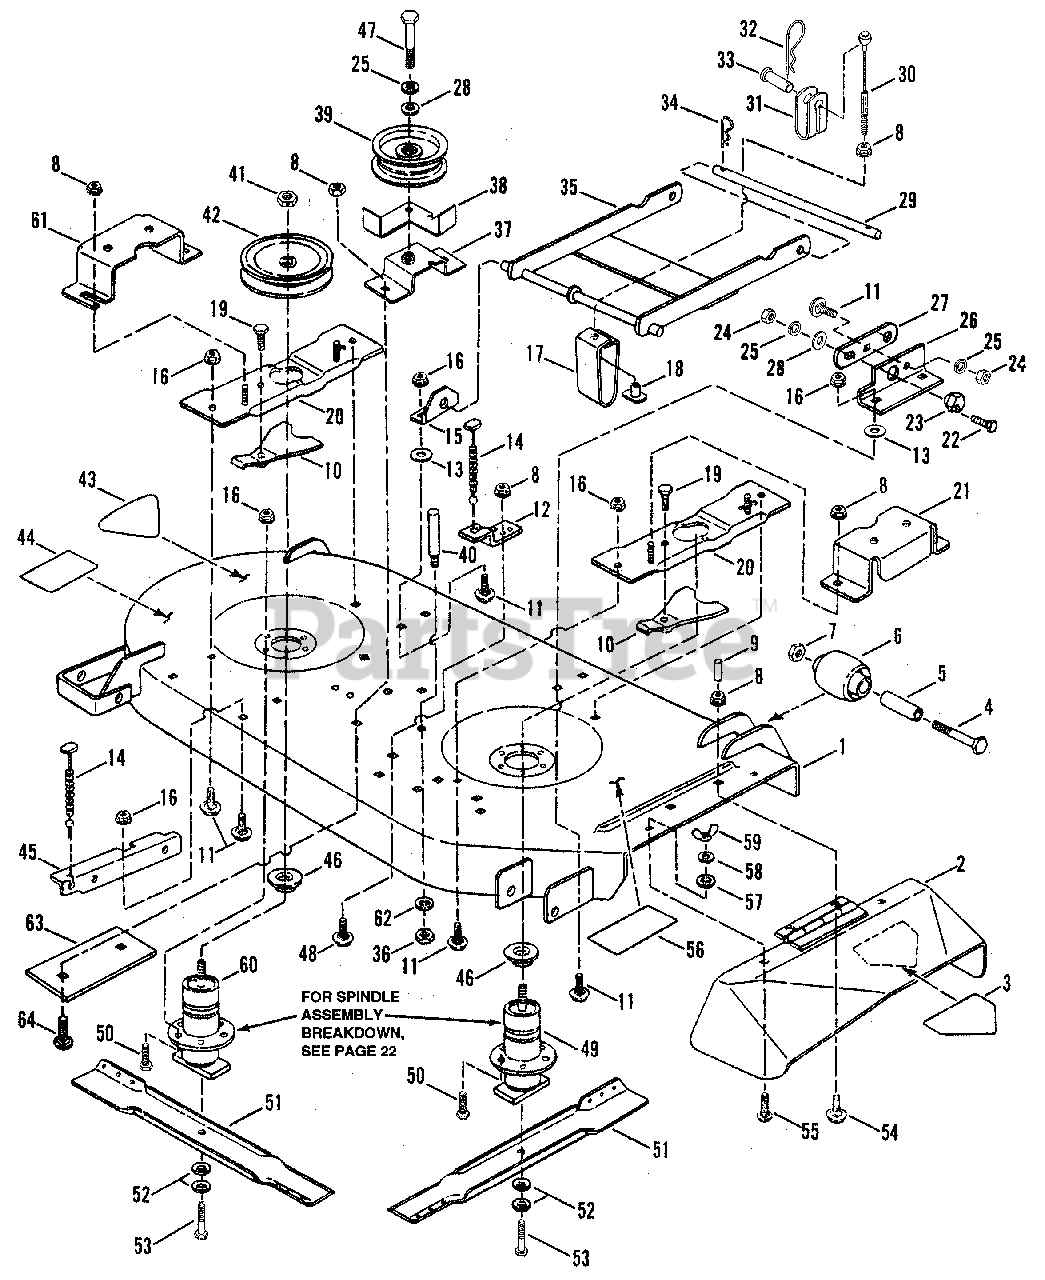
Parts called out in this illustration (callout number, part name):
1	DECK, 42" Cutting
2	DEFLECTOR, Side Discharge
3	DECAL - DANGER
4	SCREW, 3/8-24 x 3 3/4" Hex Head Cap
5	SPACER
6	WHEEL, Gage
7	NUT, 3/8-24 Hex Lock
8	NUT, 5/16-18 Hex Flange Lock
9	CAP, Vinyl
10	ASSEMBLY, Spindle Lock
11	BOLT, 3/8-16 x 3/4" Carriage
12	SUPPORT, Deck, Front (Left Side)
13	WASHER, Flat
14	CABLE, Deck Support (3.38")
15	BRACKET, Front Hanger (Left Side)
16	NUT, 3/8-16 Hex Flange Lock
17	BRACKET, Front Lift Arm Hanger
18	T-NUT, 5/16-18
19	BOLT, 3/8-16 x 1" Hex Fl. Lock
20	ASSEMBLY, Spindle Brace
21	GUARD, Pulley (Right Hand)
22	SCREW, 3/8-16 x 1" Hex Head Cap
23	ECCENTRIC, Leveling
24	NUT, 3/8-16 Hex
25	WASHER, 3/8 Split Lock
26	BRACKET, Front (Right Side)
27	LINK, Adjustment
28	WASHER, 3/8" Flat
29	PIN, Deck Hanger
30	CABLE, Deck Lift (4.75")
31	CLEVIS, Lift Cable
32	PIN, Hair, 3/32 x 1 1/2"
33	PIN, 3/8 x 1 1/16" Clevis
34	PIN, Hair, .148 x 2.62"
35	ASSEMBLY, Front Hanger
36	NUT, 3/8-24 Hex
37	BRACKET, Idler
38	GUIDE, Belt
39	PULLEY, Idler
40	STUD, Idler
41	NUT, 3/4-16 Hex Jam
42	PULLEY, Spindle
43	DECAL, 42" Deck
44	DECAL - CAUTION (Rotating Blades)
45	ASSEMBLY, Rear Support
46	WASHER, Spindle
47	BOLT, 3/8-24 x 2" Hex Hd. Cap, Gr. 5
48	BOLT, 5/16-18 x 3/4" Carriage
49	ASSEMBLY, Spindle (Right Hand)
50	BOLT, 3/8-16 x 3/4" Hex Fig. Lk.
51	BLADE, 21" Cutter
52	WASHER, Cone, 13/32 x 1 13/32" Dia.
53	SCREW, 3/8-24 x 1 1/4" Hex Head Cap, Grade 5
54	BOLT, 5/16-18 x 1" Short Neck Carriage
55	BOLT, 5/16-18 x 5/8" Carriage
56	DECAL - CAUTION (Deflector in Place)
57	RETAINER, 5/16 Bolt
58	WASHER, 5/16 Split Lock
59	WING-NUT, 5/16-18
60	ASSEMBLY, Spindle (Left Hand)
61	GUARD, Pulley (Left Hand)
62	WASHER, 3/8 Internal Tooth Lock
63	PLATE, Support
64	SCREW, 5/16-18 x 1" Hex Head Cap
